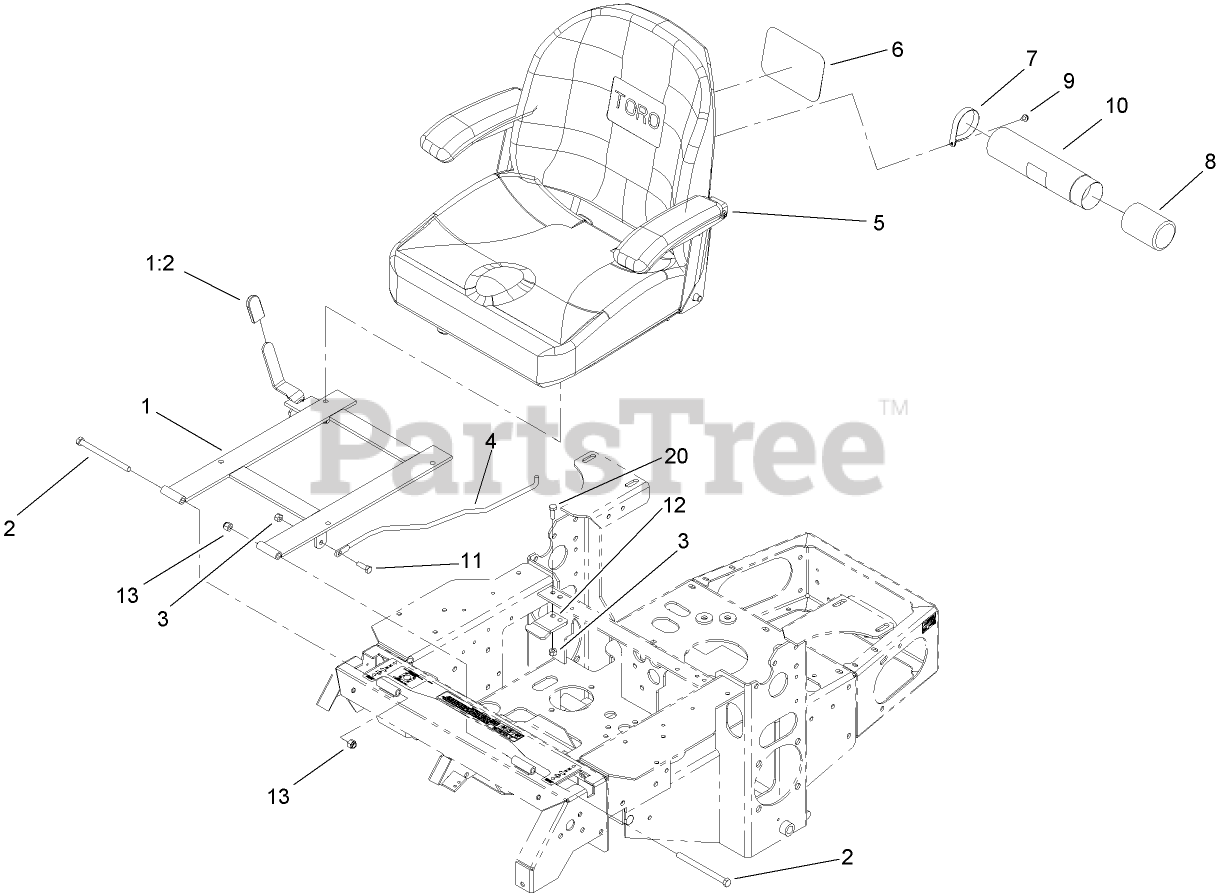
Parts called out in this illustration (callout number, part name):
1	SEAT FRAME AND LATCH ASM
1:2	GRIP-LEVER
2	SCREW-HH
3	NUT-LOCK, NI
4	ROD-RETAINER, SEAT
5	SEAT ASM
6	DECAL
7	CLAMP-R
8	CAP-HOUSING
9	SCREW-HWHTF
10	TUBE-MANUAL
11	SCREW-HH
12	CATCH-LATCH, SEAT
13	NUT-LOCK, NI
20	SCREW-HH
